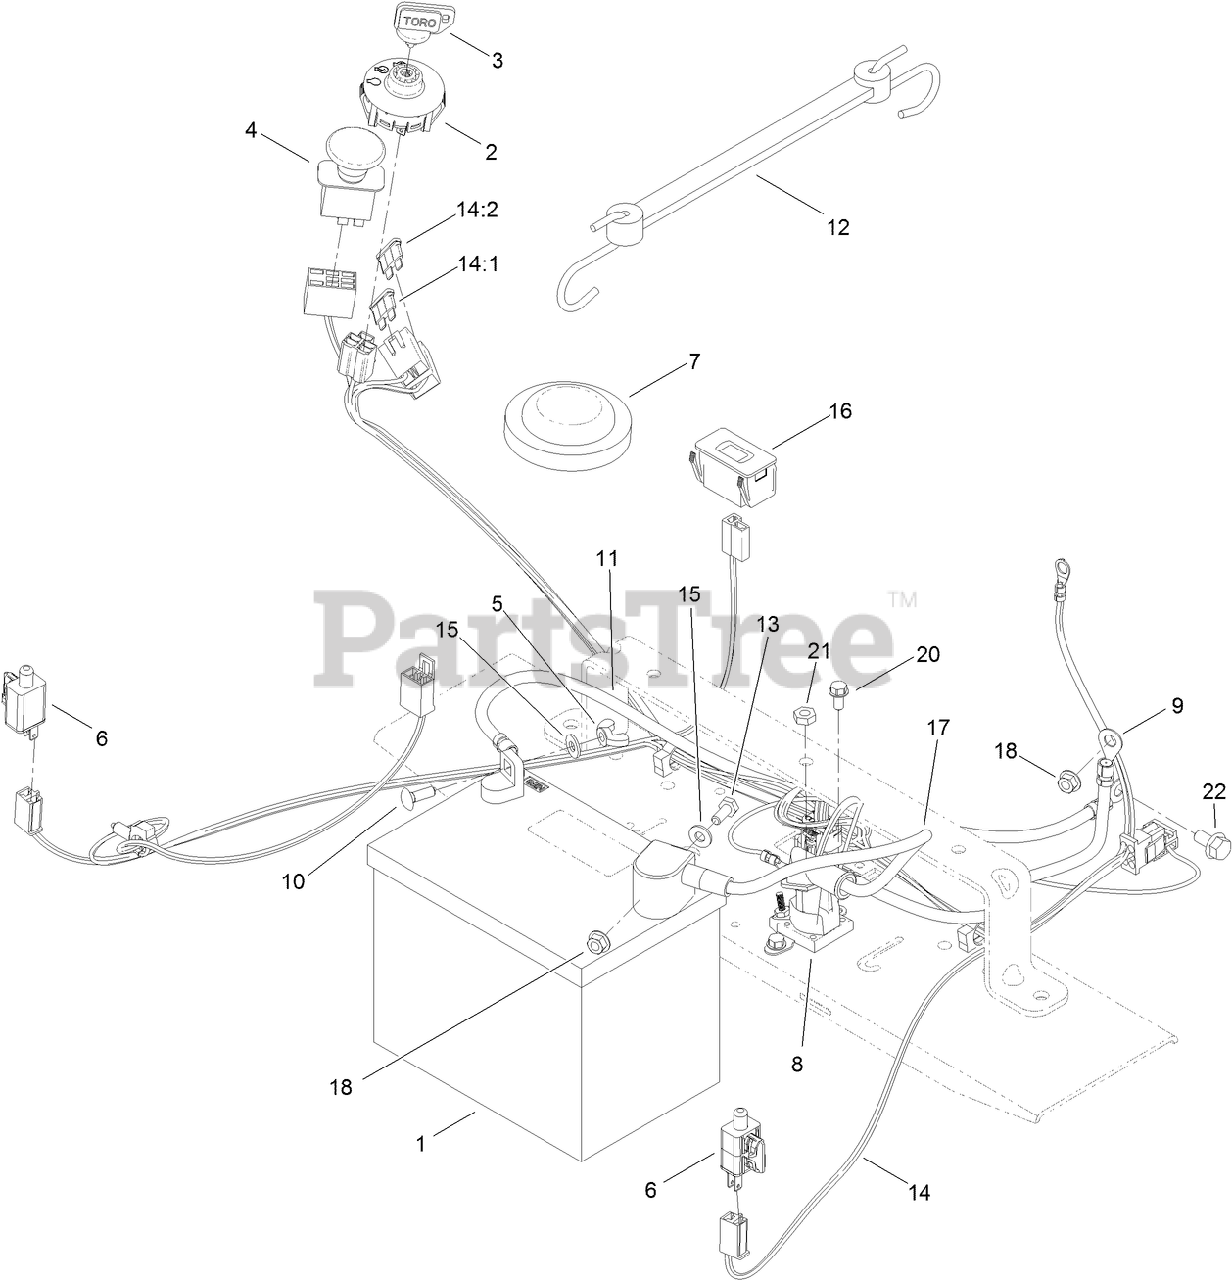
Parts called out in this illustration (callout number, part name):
1	BATTERY
3	KEY-IGNITION
4	SWITCH-PTO
5	NUT-WING
6	SWITCH
7	SWITCH-SEAT
8	SOLENOID
9	CABLE-BATTERY, RED
10	BOLT-CARR
11	CABLE-BATTERY, BLACK
12	HOLDDOWN-BATTERY
13	SCREW-HH
14:1	FUSE-BLADE, 30 AMP
14:2	FUSE-BLADE, 25 AMP
15	WASHER-FLAT
16	HOURMETER
17	CABLE-BATTERY, RED
18	NUT-HF
20	SCREW-HWH
21	NUT-JAM
22	SCREW-HHF
